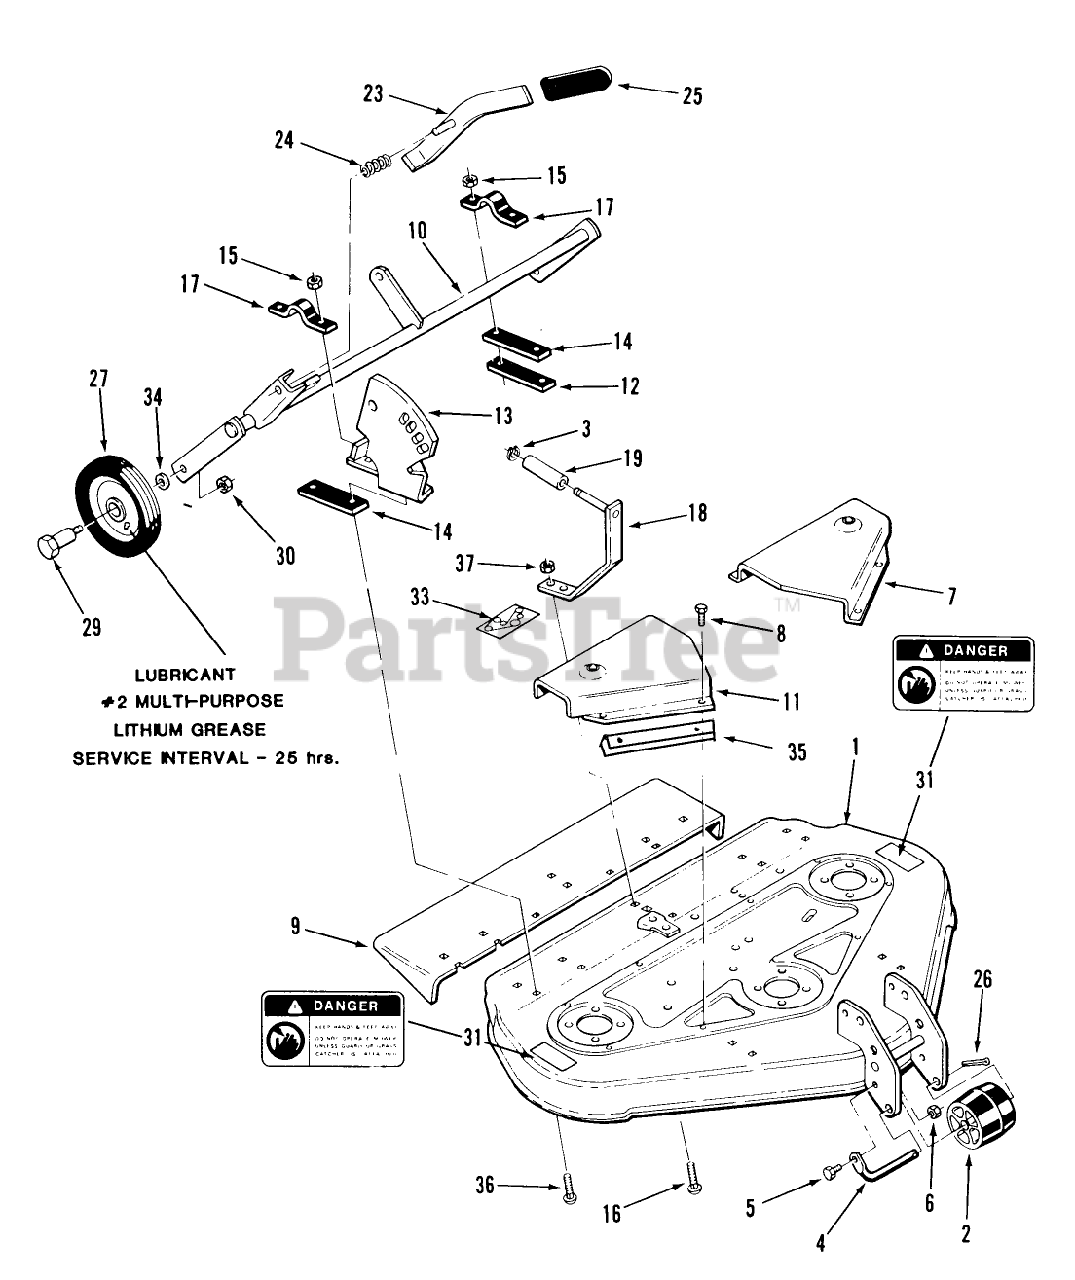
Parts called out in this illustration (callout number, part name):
2	ROLLER ASSY
4	ROLLER-SHAFT
10	ASSY GAGE WHEEL S *R
14	STRAP 1/16 *B
17	CLAMP
18	ASSY BRACKET GUID *R
24	SPRING-COMPRESSION
27	WHEEL ASM
29	BOLT-SHOULDER
33	DECAL-HEIGHT BELT
34	WASHER
